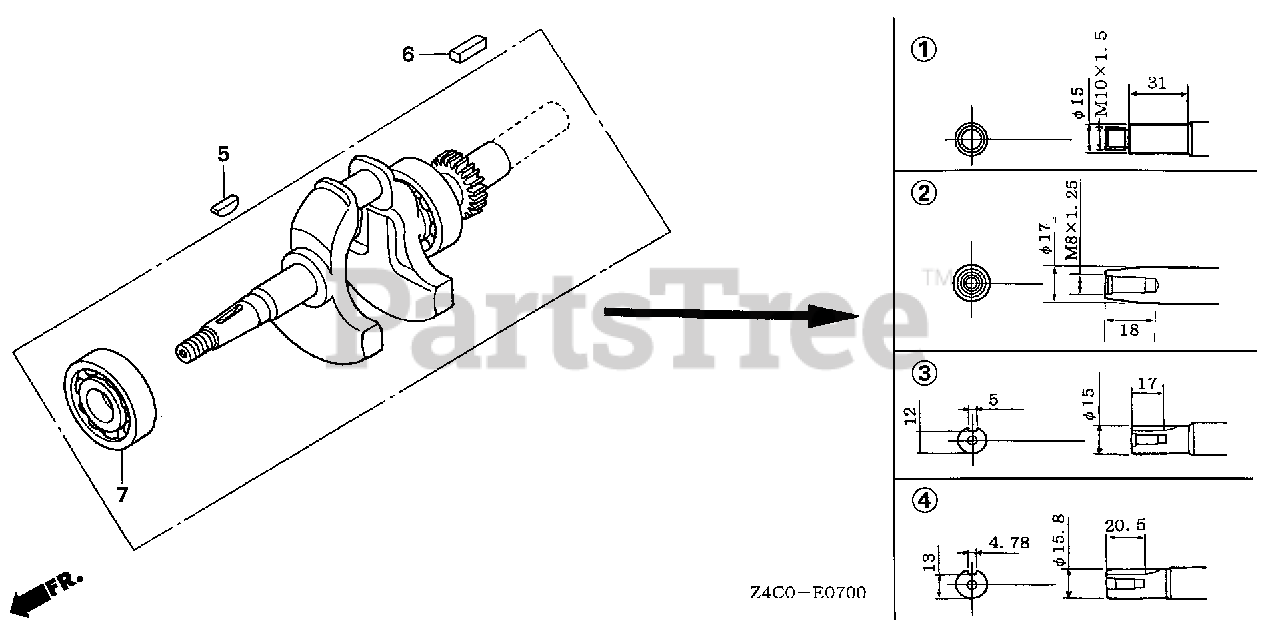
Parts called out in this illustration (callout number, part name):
4	CRANKSHAFT
5	KEY, SPECIAL
6	KEY (4.78MM)
7	BEARING, RADIAL BALL (6203)
